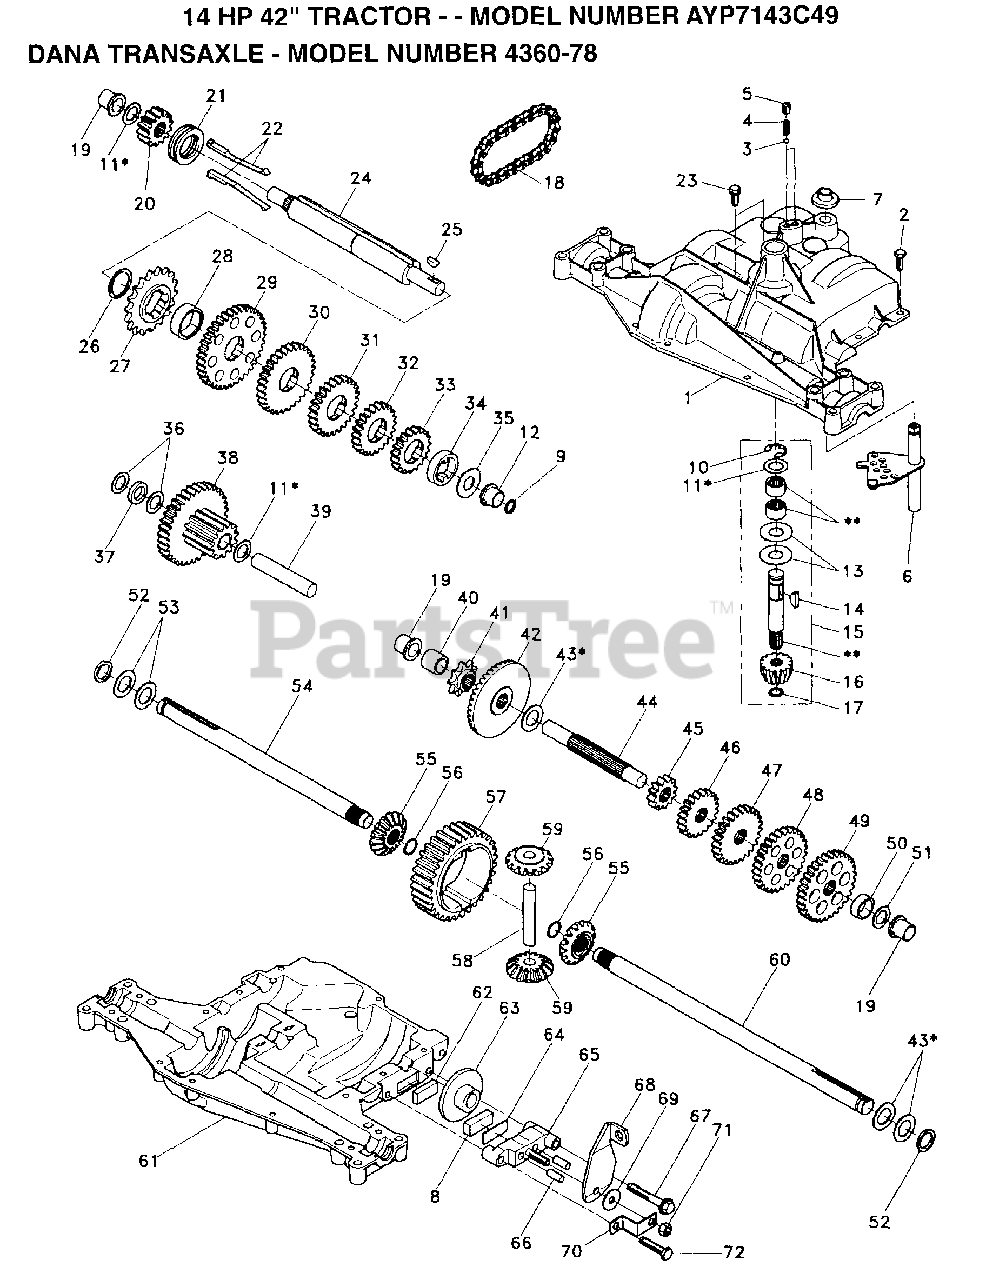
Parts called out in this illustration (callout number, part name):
1	HOUSING, UPPER
3	BALL, DETENT
4	SPRING, DETENT
5	SCREW, SET
6	SHIFTER ASSEMBLY
7	BOOT, SHIFTER
8	PUCK, FRICTION
10	RING, RETAINING
11	ASSY, KIT, SHIM .625 SHAFT
12	BEARING, FLANGE
13	WASHER, PLAIN .632 X 1.38 X .046
14	KEY, WOODRUFF, #9
15	ASSEMBLY, KIT, INPUT SHAFT
16	PINION, BEVEL, 14 TEETH
17	RING, RETAINING
18	CHAIN, 24 PITCHES
19	BEARING, FLANGE
20	GEAR, SPUR, 14 TEETH
21	COLLAR, CLUTCH
22	ASSEMBLY, KIT, CLUTCH KEYS
23	SCREW TAPPING WITH SEALER
24	SHAFT, INTERMEDIATE
25	KEY, WOODRUFF, #61
26	RING, RETAINING
27	SPROCKET, 18 TEETH
29	GEAR, SPUR, 37 TEETH
30	GEAR, SPUR, 30 TEETH
31	GEAR, SPUR, 25 TEETH
32	GEAR, SPUR, 22 TEETH
33	GEAR, SPUR, 19 TEETH
35	WASHER, PLAIN .640 X 1.37 X .061
36	WASHER, PLAIN .632 X 1.00 X .026
37	SPACER .630 X 1.00 X .169
38	ASSY GEAR COMB 12&35 TEETH
39	ASSY GEAR COMB 12&35 TEETH
39	SHAFT, IDLER
40	SPACER .635 X .875 X .755
41	SPROCKET, 9 TEETH
42	GEAR, BEVEL, 42 TEETH
43	ASSY, KIT, SHIM .750 SHAFT
44	SHAFT, DRIVE
45	GEAR SPUR, 12 TEETH
46	GEAR, SPUR, 20 TEETH
47	GEAR, SPUR, 25 TEETH
48	GEAR, SPUR, 28 TEETH
49	GEAR, SPUR, 31 TEETH
51	WASHER, PLAIN .632 X 1.00 X .060
52	WASHER, NEOPRENE
53	WASHER, PLAIN .758 X 1.25 X .031
54	AXLE LEFT HAND
55	GEAR, MITER, 15 TEETH
56	RING, RETAINING
57	GEAR, SPUR, 32 TEETH
58	SHAFT, CROSS
59	GEAR, MITER, 15 TEETH
60	AXLE, R.H.
61	HOUSING, LOWER
62	PUCK, FRICTION
63	DISC, BRAKE
65	JAW, BRAKE
66	PIN, DOWEL
67	SCREW, SELF-TAPPING
68	LEVER ACTUATING
69	WASHER, PLAIN .321 X 1.00 X .055
70	BRACKET, ANTI-ROTATION
71	LOCKNUT 5/16-24
72	SCREW TAPPING
